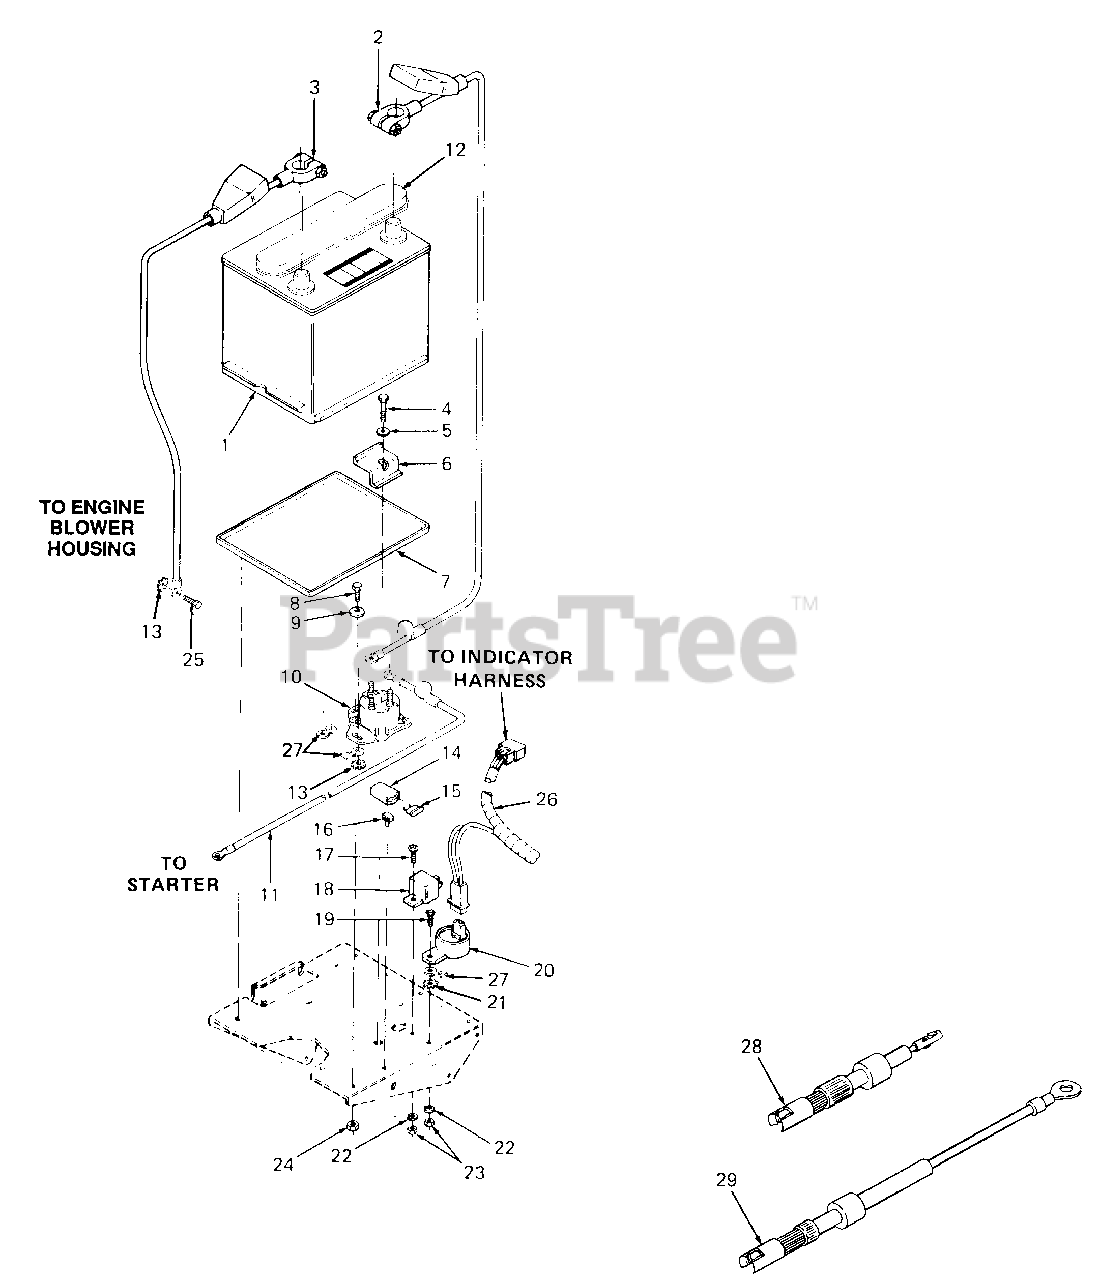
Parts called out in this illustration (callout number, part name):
1	Battery
2	Cable, Positive Battery
3	Cable, Negative Battery
4	Screw, Hex Cap, 5/16-18 X 1.38 Lg
5	Washer, Flat, .34 X .68 X .062 Thk
8	Screw, Hex Cap, 1/4-20 X .62 Lg GR5
9	Washer, Bell, .265 X .75 X .062 Thk
10	Solenoid
11	Cable, Starter
12	Cap, Battery Vent
13	Washer, Int-Ext, 1/4
14	Holder, Fuse
15	Fuse, 20 Amp
16	Clip, Fuse Holder Mtg
17	Screw, Truss Mach, #10-24 X .50 Lg
18	Relay
19	Screw, Truss Mach, #10-24 X .50 Lg
20	Indicator, Voltage
21	Washer, External, #10
22	Washer, Lock, #10
23	Nut, Hex, #10-24
24	Nut, Hex Center Lock, 1/4-20
25	Screw, Sems
26	Main Harness
27	Lug, Quick Connect
28	Diode Assy
29	Diode Assy
